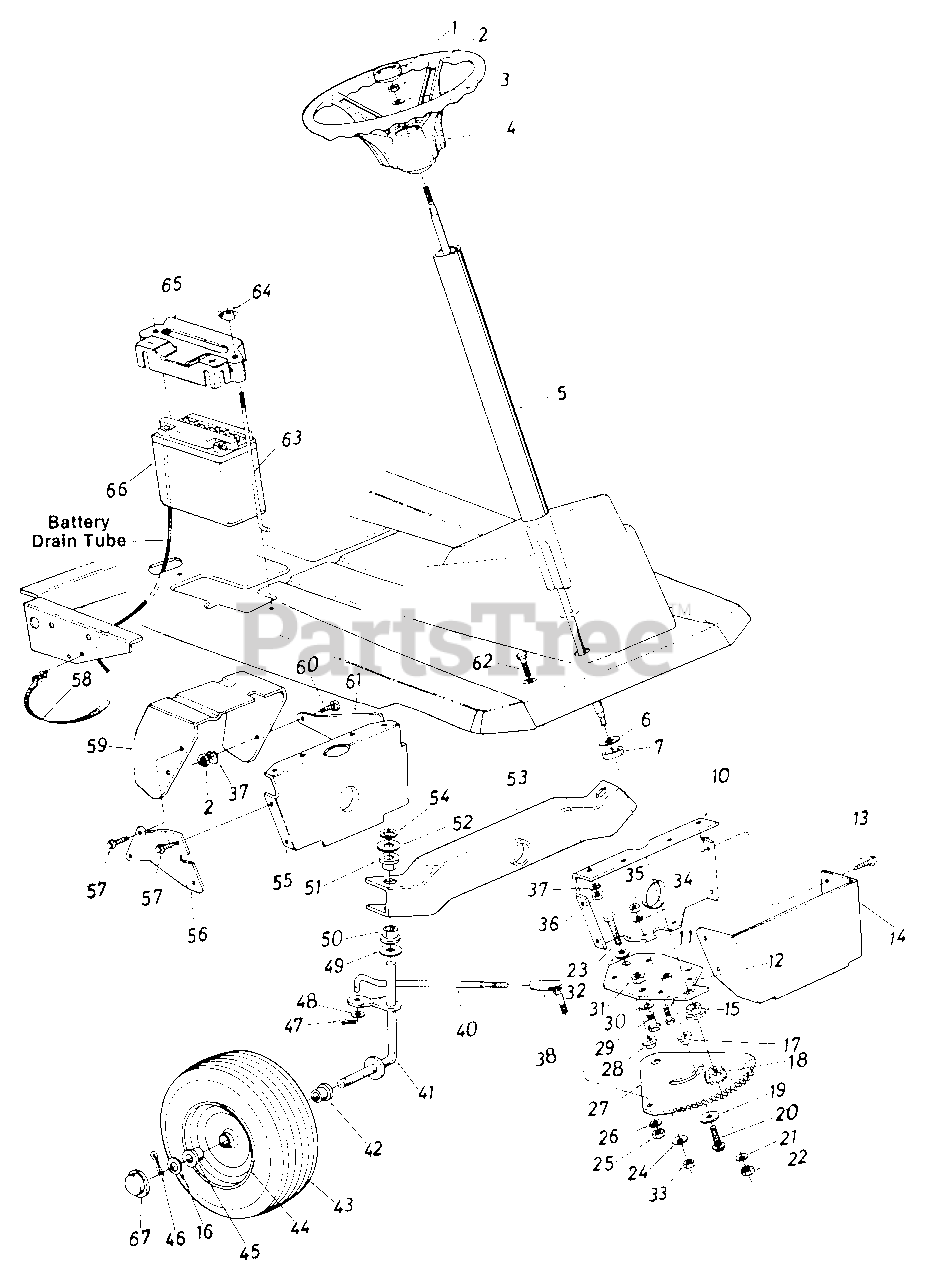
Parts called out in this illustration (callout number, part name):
1	CAP-STEER WHEEL
2	NUT-HEX 5/16-18
3	WASHER-BELL .337 X .867 X .057
4	STEERING WHEEL ASSY
5	SHAFT ASSY
6	WASHER-FL-.640ID X 1.24OD X .06HDN
7	SPACER
10	BRACKET-PIVOT BAR
11	SCREW-HEX 5/16-18 X .75
12	BRACKET-ST GEAR SUP
13	SCREW-HEX WASH HD
16	WASHER-.63IDX1.595ODX.62
18	GEAR-PINION
20	SCREW-HEX SLF TAP 3/8 X 1 3/8
21	WASHER-BELL .337 X .867 X .057
22	NUT-5/16-24
23	SCREW 3/8-24X1.25 GR5
25	NUT-HEX 3/8-24
26	WASHER-LOCK-3/8
27	SEGMENT-STEERING
29	SCREW-NYLON
30	WASHER-FL-.531 X .930 OD X .050
31	NUT-HEX 1/2-13
32	WASHER-BELL .400 ID X .88 X .060
33	NUT-HEX 3/8-24
34	WASHER-LOCK-5/16
35	NUT-HEX 5/16-18
36	NUT-HEX 5/16-18
37	WASHER-LOCK-5/16
38	JOINT ASSY-BALL
40	ROD-STEER TIE
41	AXLE ASSY-RH
42	BEARING-FLANGE
43	WHEEL
44	WHEEL RIM
45	BEARING-FLANGE
46	PIN-COTTER-1/8 DIA X 1.25
47	PIN-COTTER-1/8 DIA X 1.00
48	WASHER-FL-.385 ID X .87 OD X .06
49	WASHER-FL-.635 ID X 1.12 OD X .090
50	BEARING-FLANGE
51	BEARING-FLANGE
52	WASHER-FL-.635 ID X 1.12 OD X .090
53	BAR ASSY-PIVOT
54	NUT-PUSH-SPEED
55	BRACKET-PIVOT BAR
56	BRACKET-REINF-RH
57	SCREW-HEX WASH HD
58	TIE-PUSH MOUNT
59	PEDAL ASSY-BRAKE
60	SCREW-HEX 5/16-18 X .75
61	BRACKET-REINF-LH
62	SCREW-HEX 5/16-18 X .75
63	BATTERY HOLD DOWN
64	NUT-WING-SOLID 1/4-20
65	COVER-BATTERY
66	BATTERY
67	HUB CAP
